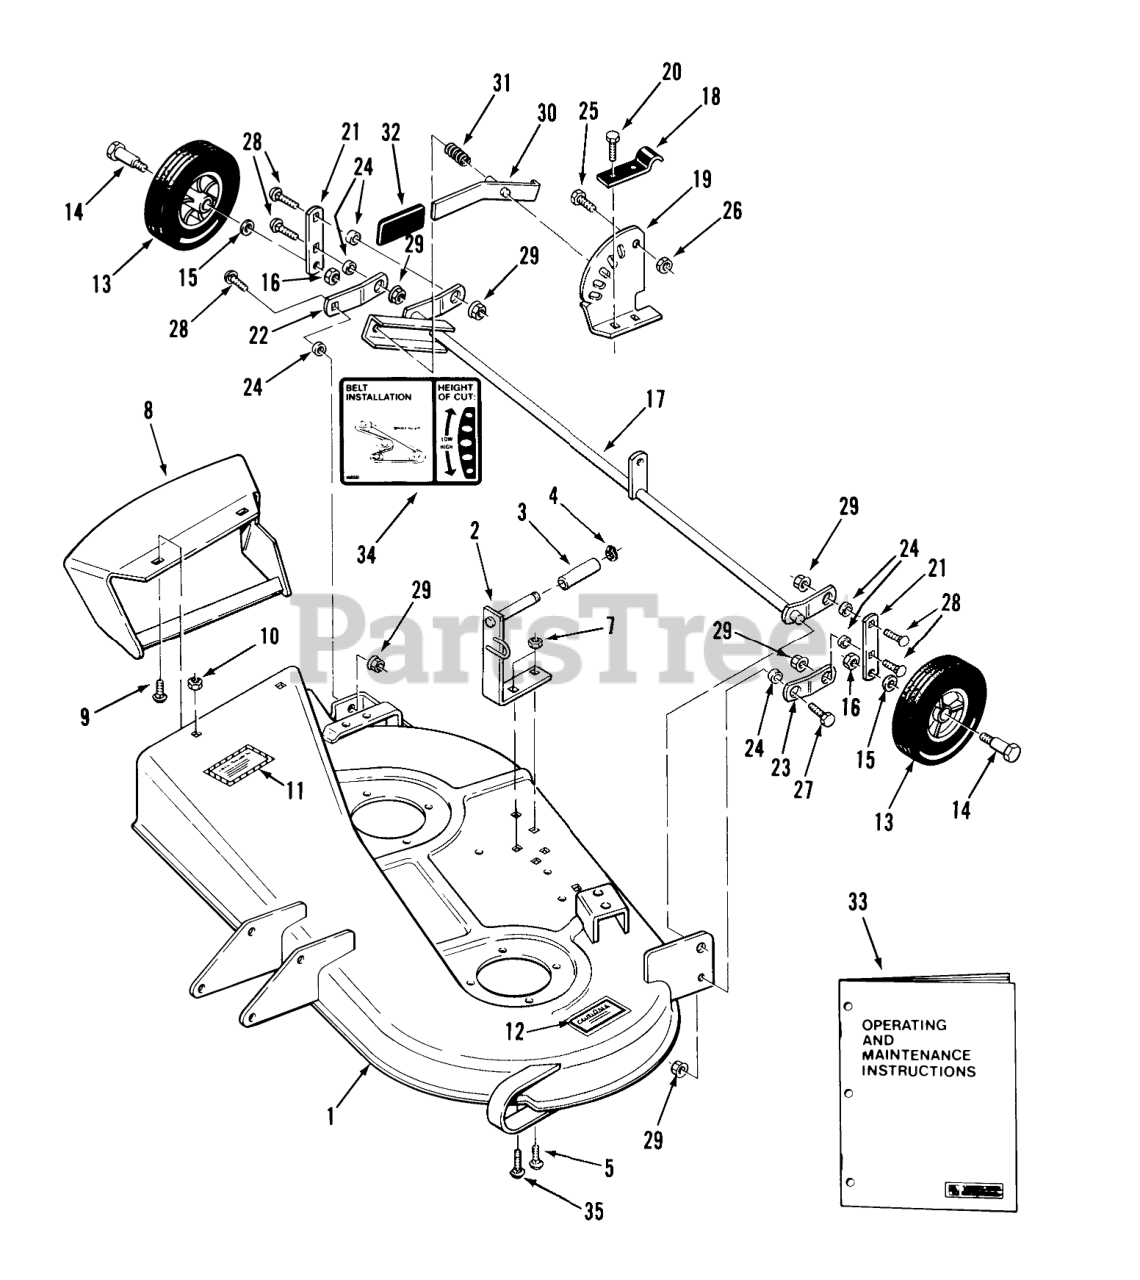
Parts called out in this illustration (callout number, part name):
1	Mower Deck
2	ASSY-BRACKET GUID R
3	SPACER
4	Snap Ring
5	CARRIAGE BOLT -9
7	Nut
8	ASSY-CHUTE EXT R
9	Bolt
10	Nut
11	DECAL
12	Caution Decal
13	WHEEL-GAUGE
15	WASHER
16	Nut
17	Gage Wheel Support
18	Bracket-Pivot
19	Quadrant
20	Bolt
21	LINK R
22	ARM-PIVOT RH R
23	Arm LH
24	SPACER
26	Nut
27	BOLT
28	Bolt
29	LOCKNUT-FLANGE
30	Lever
31	SPRING-COMPRESSION
33	Operating & Maintenance Instructions
34	DECAL-BELT&HEIGHT
35	Bolt-Carriage
